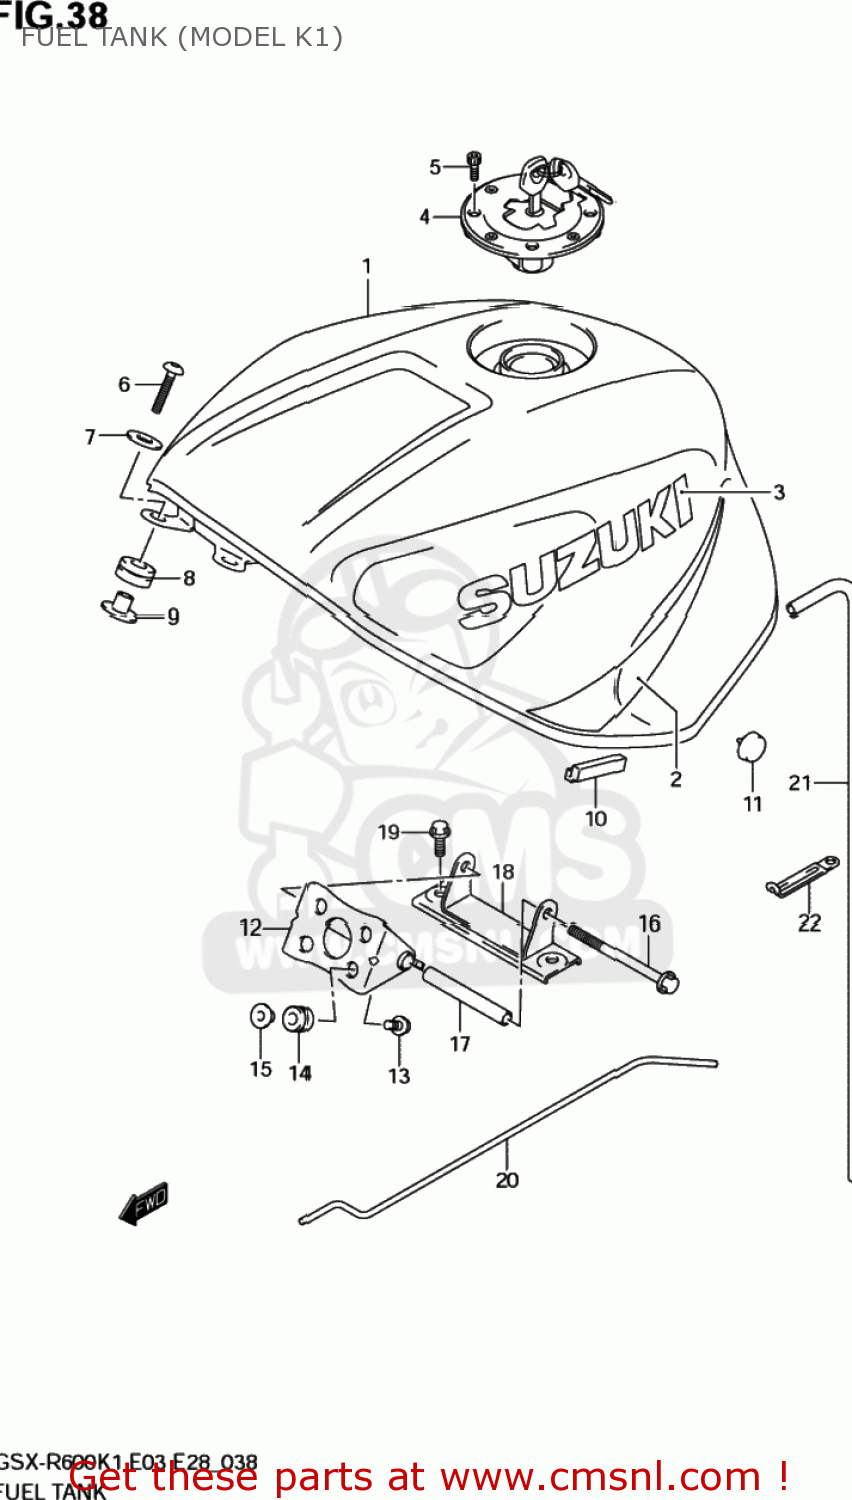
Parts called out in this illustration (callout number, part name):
1	TANK ASSY,FUEL
2	TAPE SET,FUEL
3	EMBLEM,FUEL TANK
4	CAP SET,FUEL TANK
5	BOLT(5X20)
6	SCREW(6X25)
7	WASHER(6.5X22X1.6)
8	CUSHION,FUEL TANK FR
9	SPACER,FUEL TANK FR
10	CUSHION,FUEL TANK SIDE
11	CUSHION,FUEL TANK SIDE NO.2
12	BRACKET,FUEL TANK NO.1
13	BOLT(6X20)
14	CUSHION
15	WASHER
16	BOLT
17	SPACER,FUEL TANK RR
18	BRACKET,FUEL TANK NO.2
19	BOLT
20	STAY,FUEL TANK
21	HOSE,FUEL TANK WATER DRAIN
22	CLAMP(L:65)
